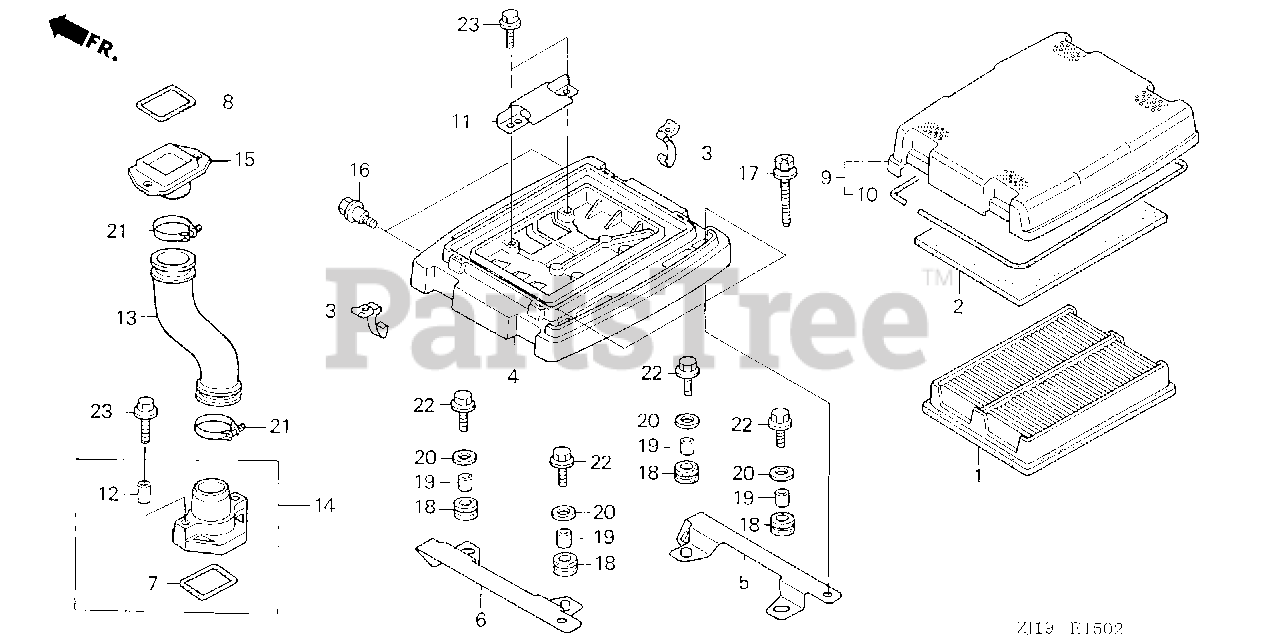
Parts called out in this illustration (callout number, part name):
1	ELEMENT COMP., AIR CLEANER
2	FILTER (OUTER)
3	CLIP, AIR CLEANER
4	HOUSING COMP., AIR CLEANER
5	STAY, R. AIR CLEANER HOUSING
6	STAY, L. AIR CLEANER HOUSING
7	SEAL, AIR CLEANER HOUSING
8	SEAL, AIR CLEANER HOUSING
9	COVER ASSY., AIR CLEANER
10	SEAL, AIR CLEANER COVER
11	PLATE, AIR CLEANER SETTING
12	COLLAR A, AIR CLEANER
13	TUBE, AIR CLEANER CONNECTING
14	JOINT ASSY., CONNECTING TUBE (B)
15	JOINT A, CONNECTING TUBE
16	BOLT, FLANGE (6MM)
17	BOLT-WASHER (5X30)
18	RUBBER, CONTROL BOX
19	COLLAR, CONTROL BOX
20	WASHER, PLAIN (6MM)
21	BAND, AIR CLEANER CONNECTING TUBE (58)
22	BOLT, FLANGE (6X20)
23	BOLT, FLANGE (6X28)
